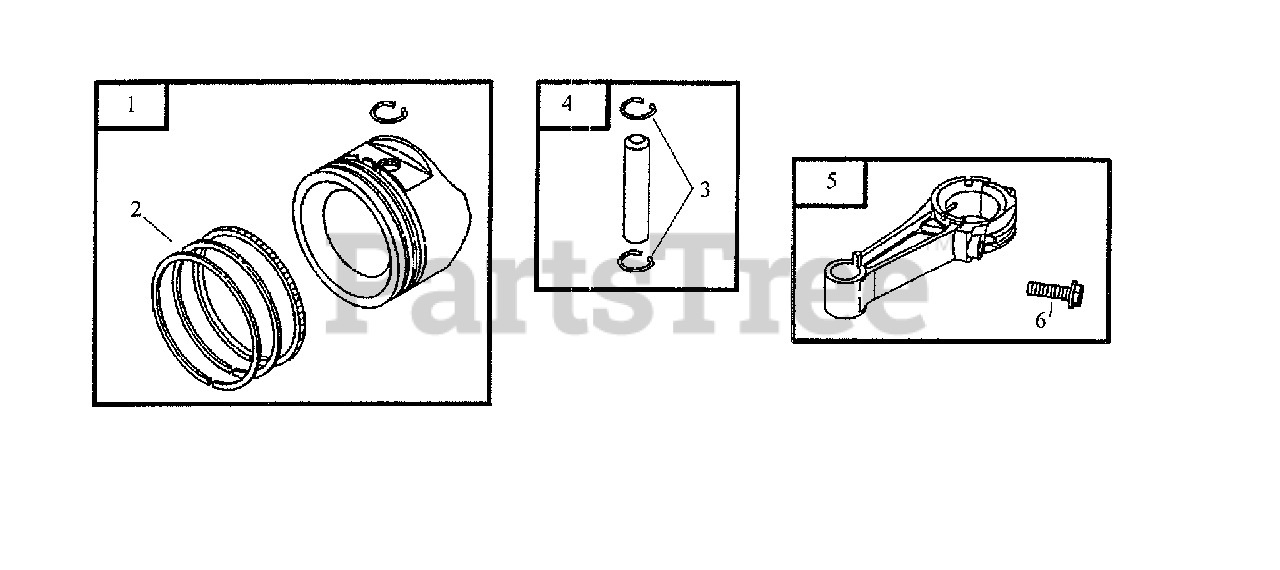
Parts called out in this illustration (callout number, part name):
1	Piston Standard
2	Ring Set Standard
3	Lock, Piston Pin
4	Piston Pin
5	Connecting Rod
